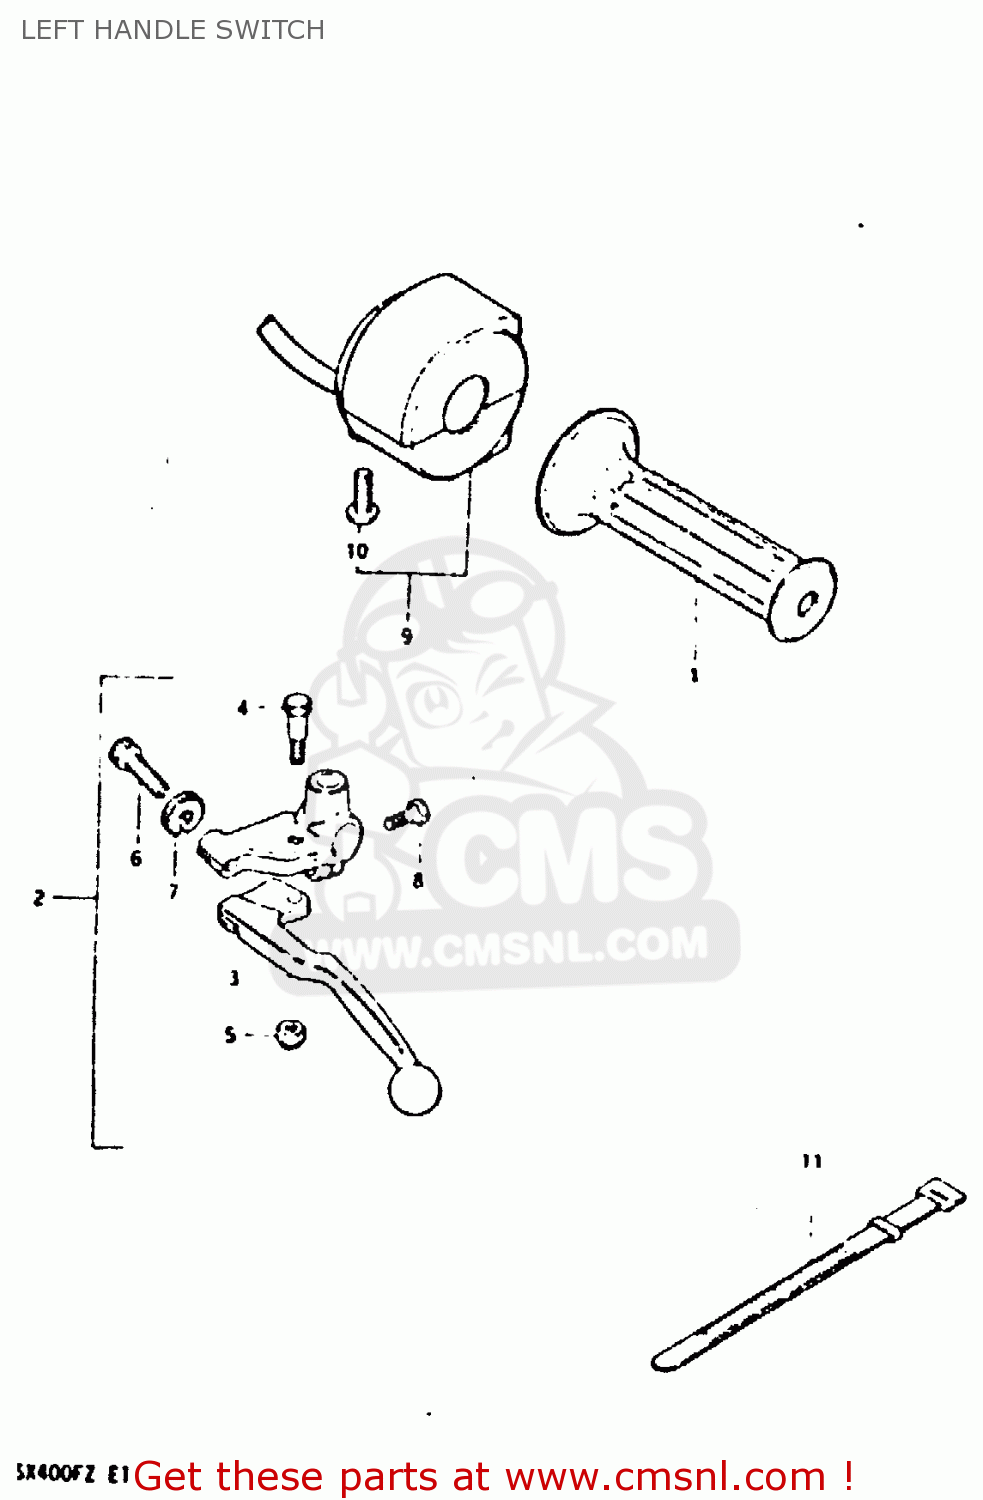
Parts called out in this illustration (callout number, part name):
1	GRIP,LEFT
2	LEVER ASSEMBLY
3	LEVER,CLUTCH
4	BOLT,LEVER
5	NUT 6MM
6	ADJUSTER,CABLE
7	NUT,CABLE ADJUSTER
8	BOLT,CLUTCH LEVER HOLDER
9	SWITCH ASSY, HANDLE LH
10	SCREW
11	CLAMP(L:120)
